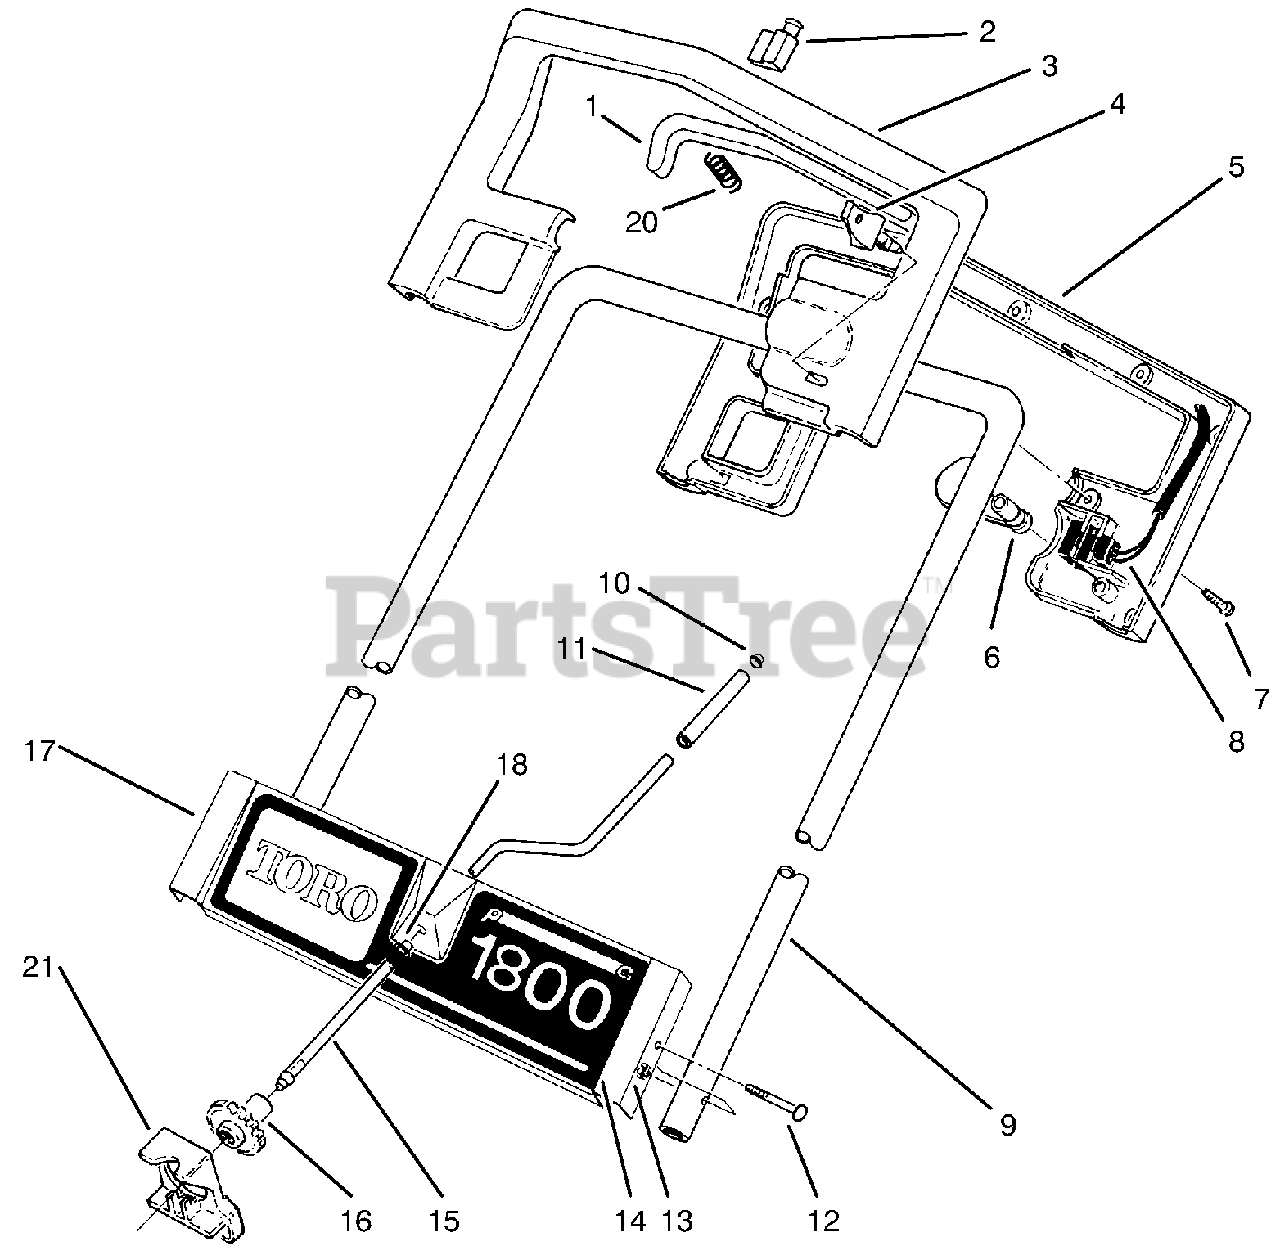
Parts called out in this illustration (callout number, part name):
1	Bar - Switch
2	SWITCH
3	Handle - Upper Control
5	Handle - Lower Control
6	Tab - Lock
7	SCREW-PPH
8	Cord - Supply
9	Tube - Upper Handle
10	PUSHNUT-CAP, WASHER
11	Sleeve - Chute Crank
12	Screw - Hex Hd. Mach.
13	NUT-LOCK
14	Decal - Escutcheon
15	Rod - Chute Crank
16	Gear - Chute Crank
17	Plate - Escutcheon
18	Bushing - Nyliner
21	Brake - Gear
